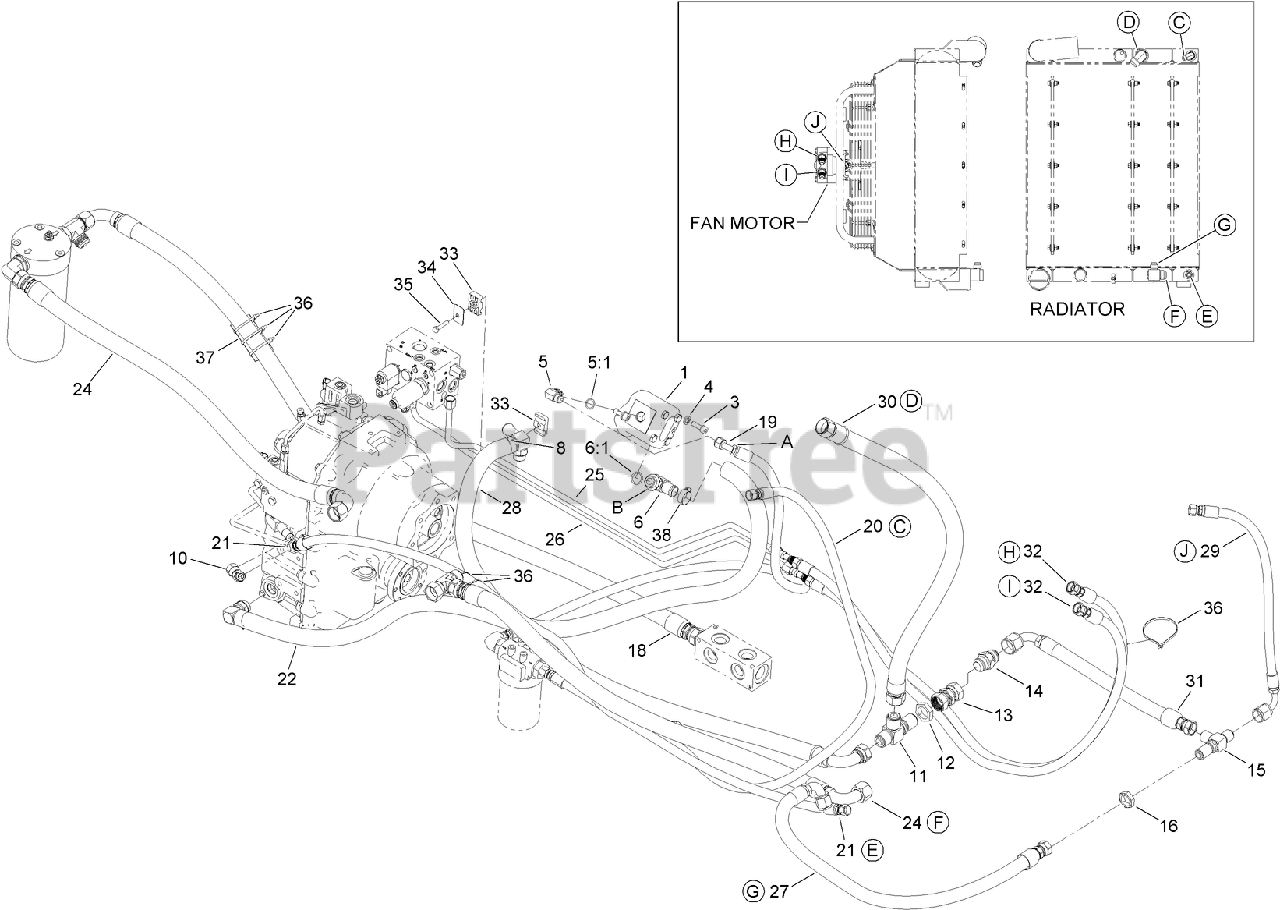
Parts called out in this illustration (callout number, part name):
1	GEAR PUMP ASM
3	SCREW-HSH
4	WASHER-HARDENED
5	FITTING-90 DEG
5:1	O-RING
6	FITTING-HYD, 90 DEG
6:1	O-RING
8	CLAMP-HOSE
10	FITTING-ELBOW, 45 DEG
11	FITTING-TEE, BULKHEAD
12	NUT-LOCK, BULKHEAD
13	FITTING-STRAIGHT
14	VALVE-CHECK
15	FITTING-TEE, BULKHEAD
16	NUT-LOCK, BULKHEAD
18	HYD HOSE ASM, LP
19	HYD HOSE ASM, HP
20	HYD HOSE ASM, HP
21	HYD HOSE ASM, LP
22	HOSE-SUCTION
24	HYD HOSE ASM, LP
25	HYD TUBE ASM
26	HYD TUBE ASM
27	HYD HOSE ASM, HP
28	HYD HOSE ASM, LP
29	HYD HOSE ASM, HP
30	HYD HOSE ASM, LP
31	HYD HOSE ASM, HP
32	HYD HOSE ASM, HP
33	CLAMP-TUBE
34	COVERPLATE
35	SCREW-HH
36	TIE-CABLE
37	PROTECTOR-HOSE
38	CLAMP-HOSE
